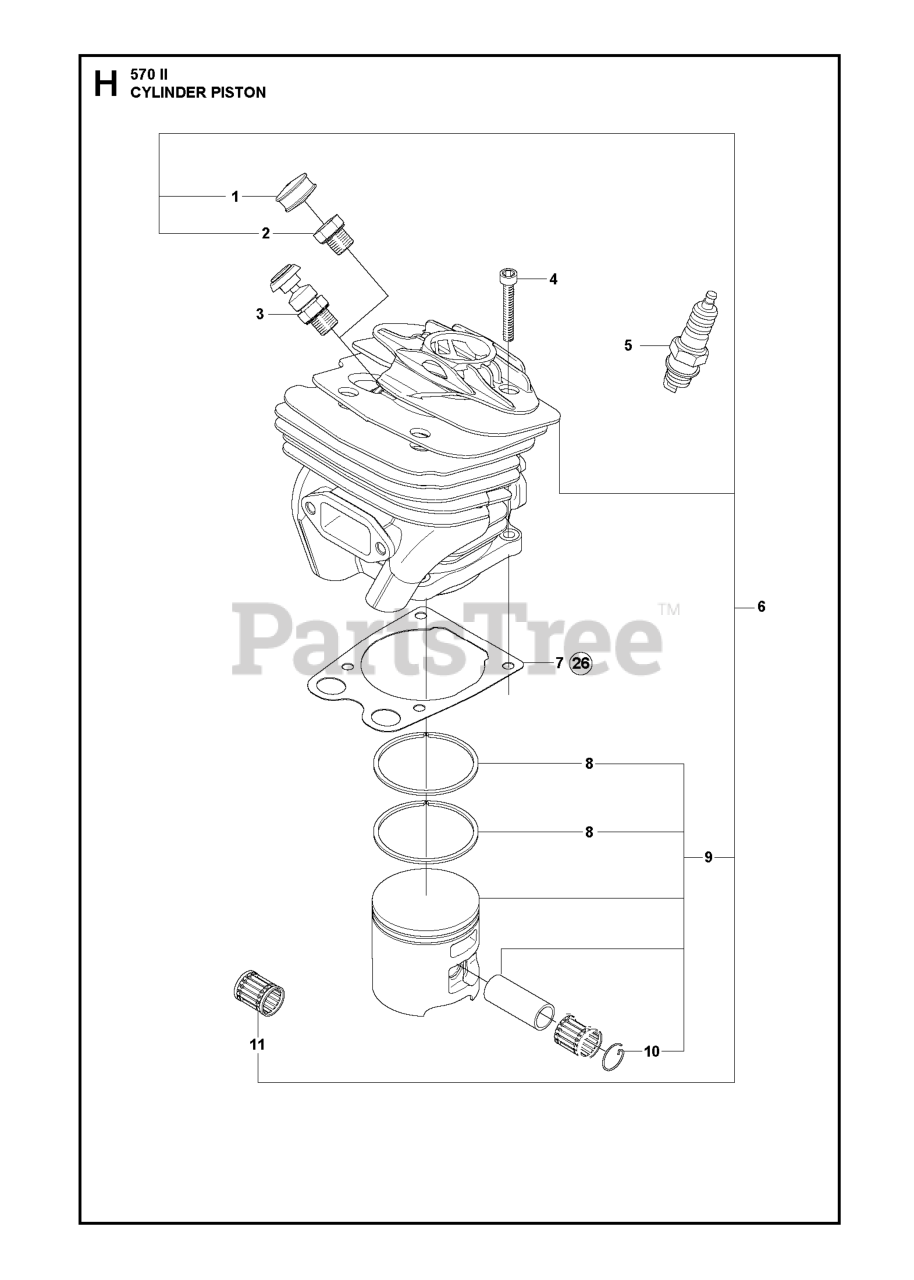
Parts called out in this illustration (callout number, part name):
2	CYLINDER PLUG
4	SCREW MC6S 5X25
5	SPARK PLUG M14X1.25 NGK BPMR7A
6	CYLINDER ASSY
8	PISTON RING
9	PISTON ASSY
10	WRIST PIN CLIP
11	NEEDLE BEARING PISTON PIN 12X1
26	GASKET KIT
